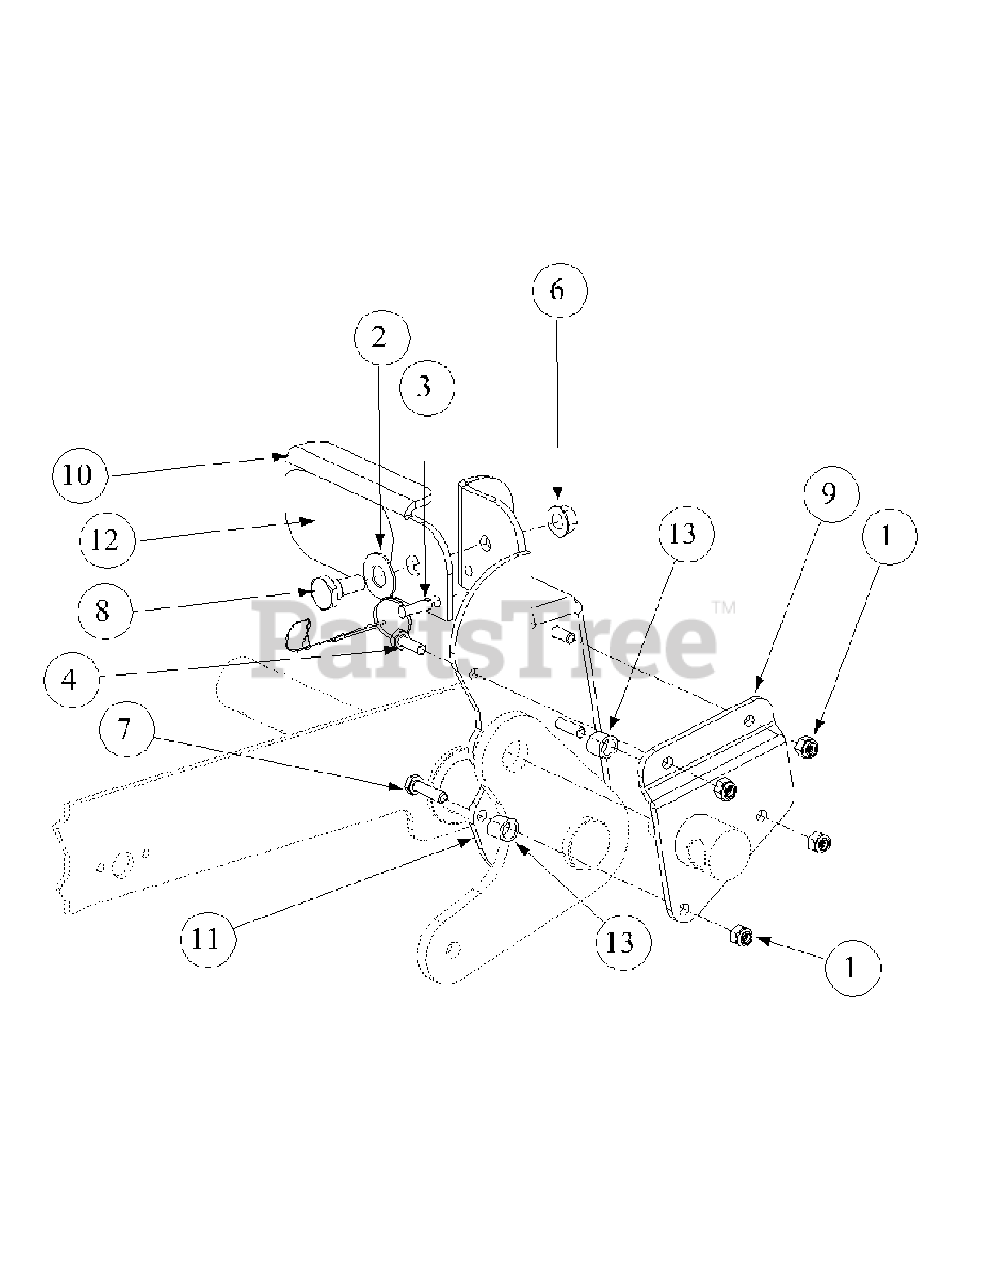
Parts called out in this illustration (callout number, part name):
1	Lock Nut, Nylon Insert, 1/4-20
2	Washer, 1/2 x 1 Shim
3	Detent Pin w/12" Lanyard
4	Hex Cap Screw, 1/4-20, .75
6	Hex Nut, Flange Lock 3/8-16
7	Hex Cap Screw, 1/4-20, 1.00
8	Shoulder Screw, .50 x .27 Lg., 3/8-16
9	Foot Lift Backup Pedal
10	Deck Lift Foot Pedal
11	Deck Lift Foot Pedal
12	Deck Lift Foot Pad
13	Turnbuckle Sleeve
